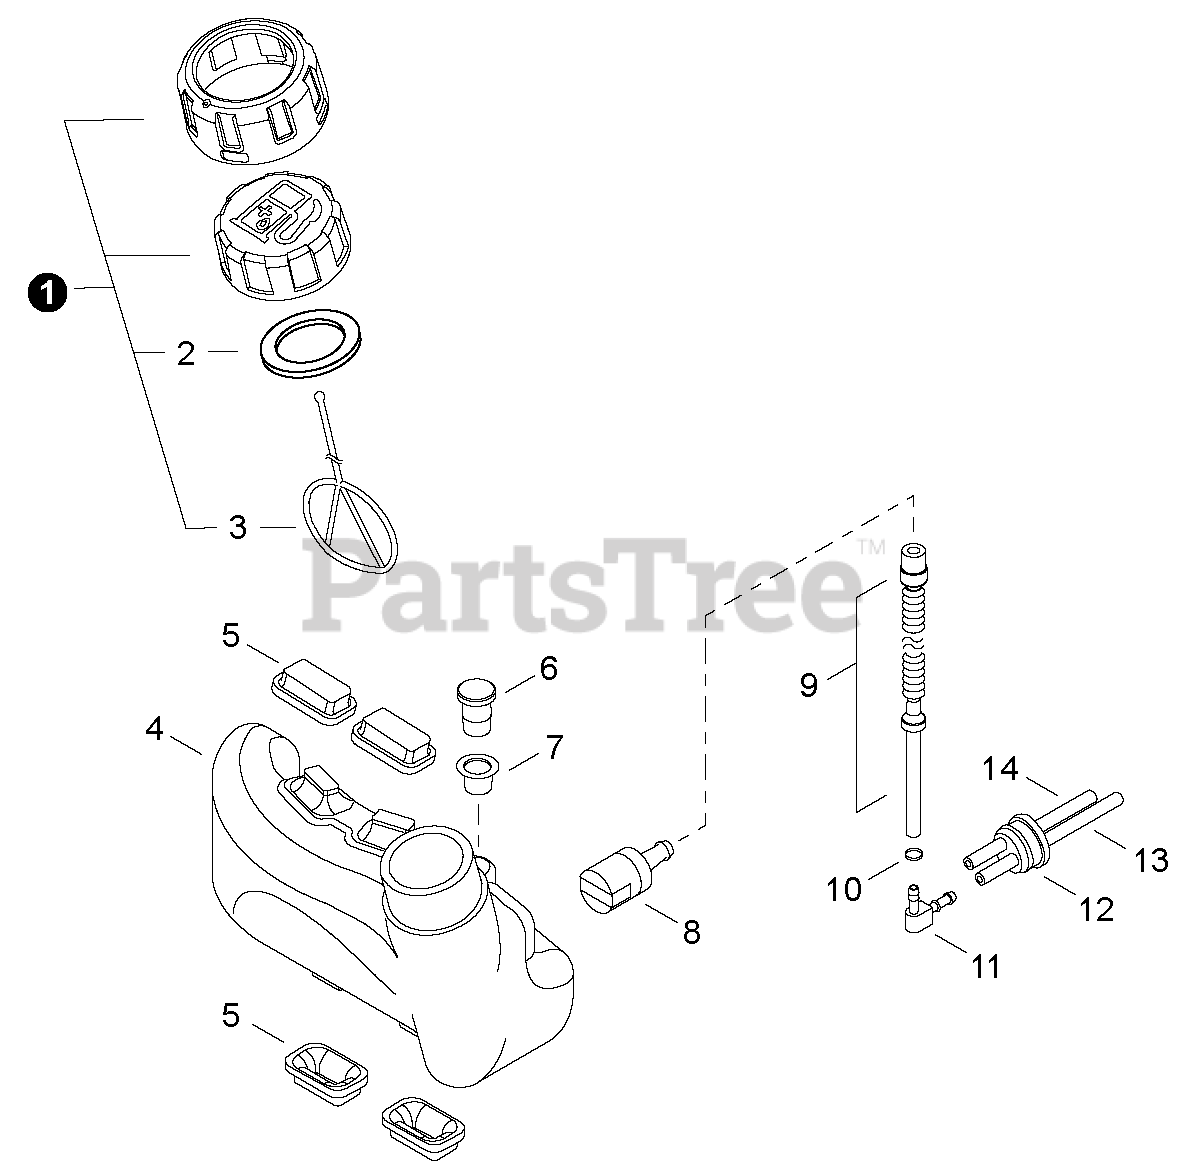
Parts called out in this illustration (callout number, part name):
1	CAP ASSY
2	GASKET, CAP
3	CONNECTOR, CAP
4	TANK, FUEL
5	CUSHION
6	VENT, FUEL TANK
7	GROMMET
8	FILTER, FUEL
9	PIPE - FUEL
10	CLIP - 6.5
11	CONNECTOR, PIPE
12	GROMMET
13	PIPE - 3X5X83 -- BLACK
14	PIPE - 3X6X85 -- CLEAR
